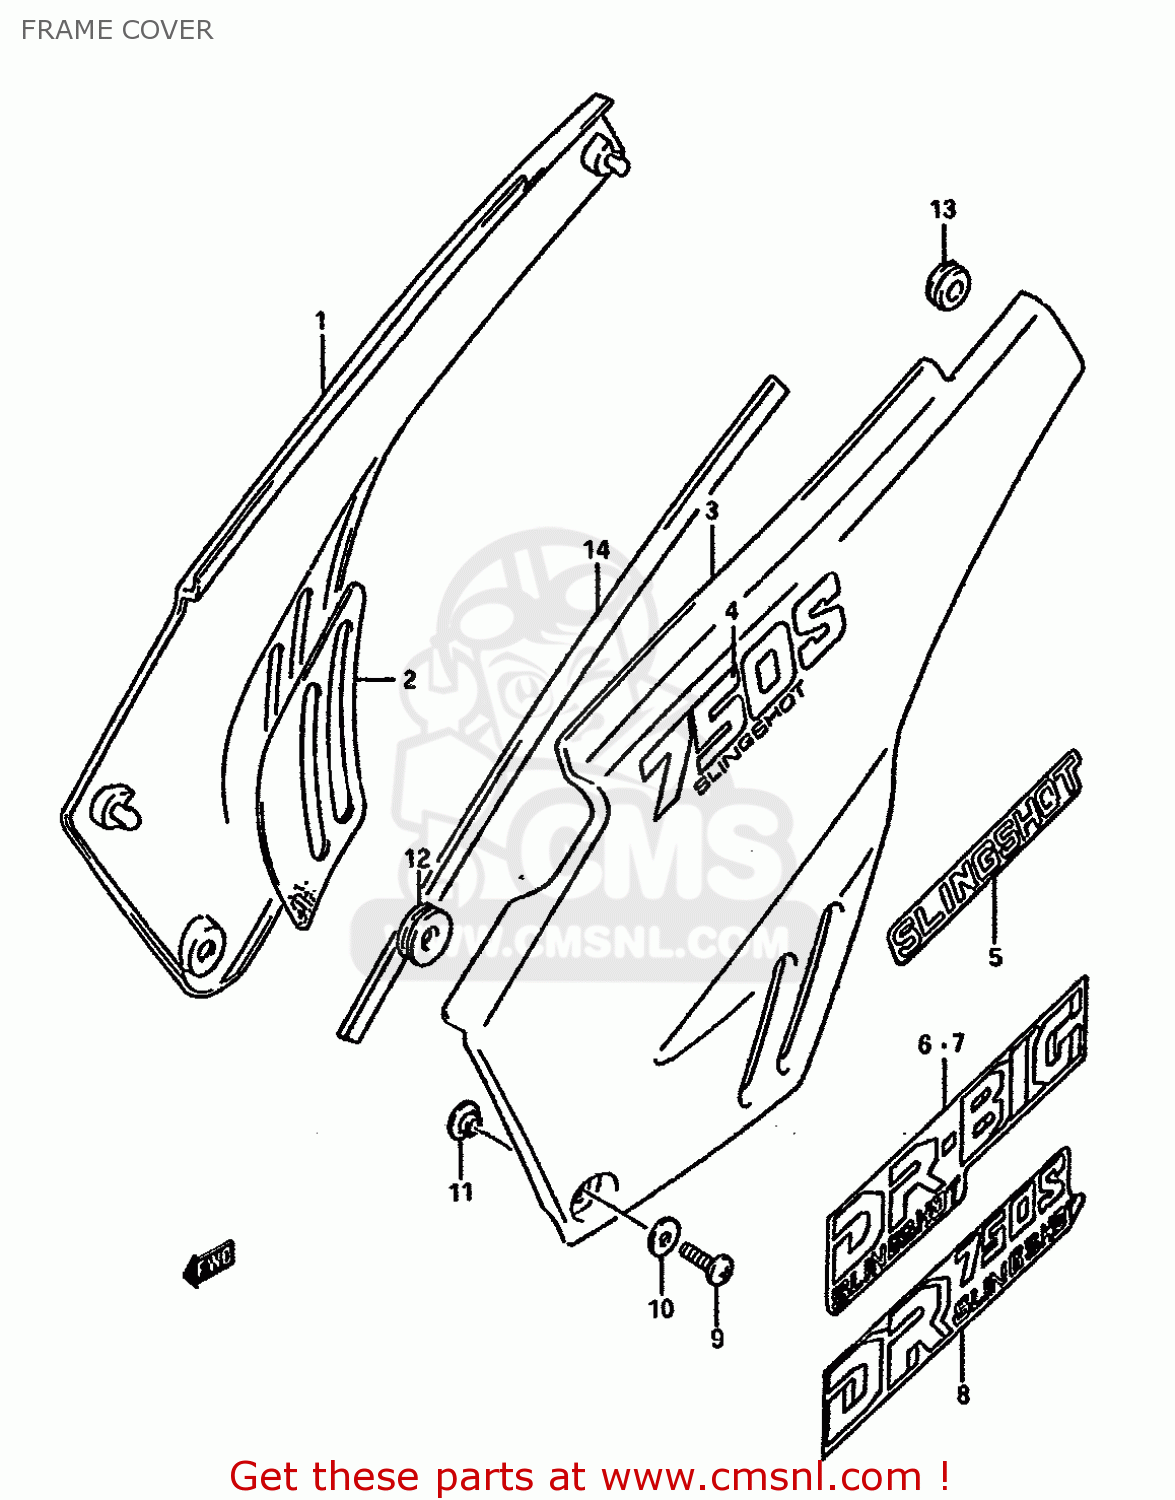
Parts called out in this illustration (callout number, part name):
1	COVER,FRAME,R(RED)
2	HEAT SHIELD,RH
3	COVER,FRAME,L(RED)
4	EMBLEM,FRAME COVER
5	EMBLEM,FRAME COVER
6	EMBLEM,RH
7	EMBLEM,LH
8	EMBLEM
9	SCREW
10	WASHER
11	WASHER
12	CUSHION
13	CUSHION
14	DUST SEAT,FRAME COVER
